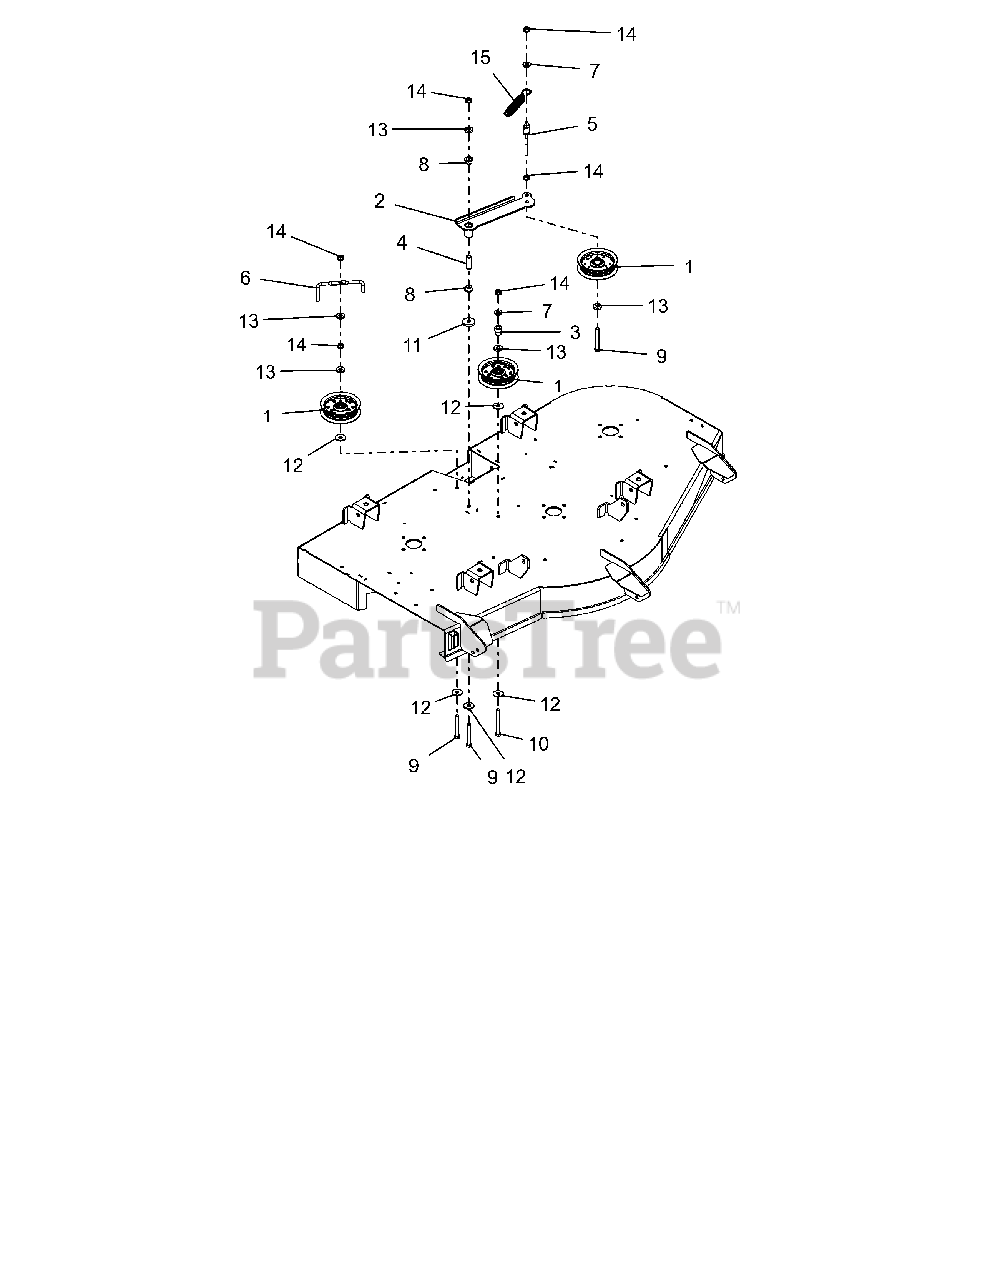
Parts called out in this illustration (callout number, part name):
1	ASM, IDLER 4"
2	WLDMT, IDLER ARM-52"
3	BUSHING, IDLER (P/M)
4	SPACER, .375IDX.625ODX1.66 PM
5	WIREFORM, BELT FINGER
6	WIREFORM, BELT FINGER
7	BSHG-FLG .385X.500X.875X.406
8	BSHG-FLG, .625X.750X.500X1.00
9	BLT-HEX .38-16X3.00 GR5 FTH YZ
10	@BLT-HEX .38-16X3.50 GR5 YWZC
11	WSHR,FLT STL.406X1.50X.245YWZC
12	WSHR FL STL .406X1.25X.10ZC120
13	WSHR-FL-STL .406X1.00X.188 YWZ
14	NUT-LK-TOP-FLG .38-16 ZC120
15	SG-TENS .135X.98X6.0 WLD 62
